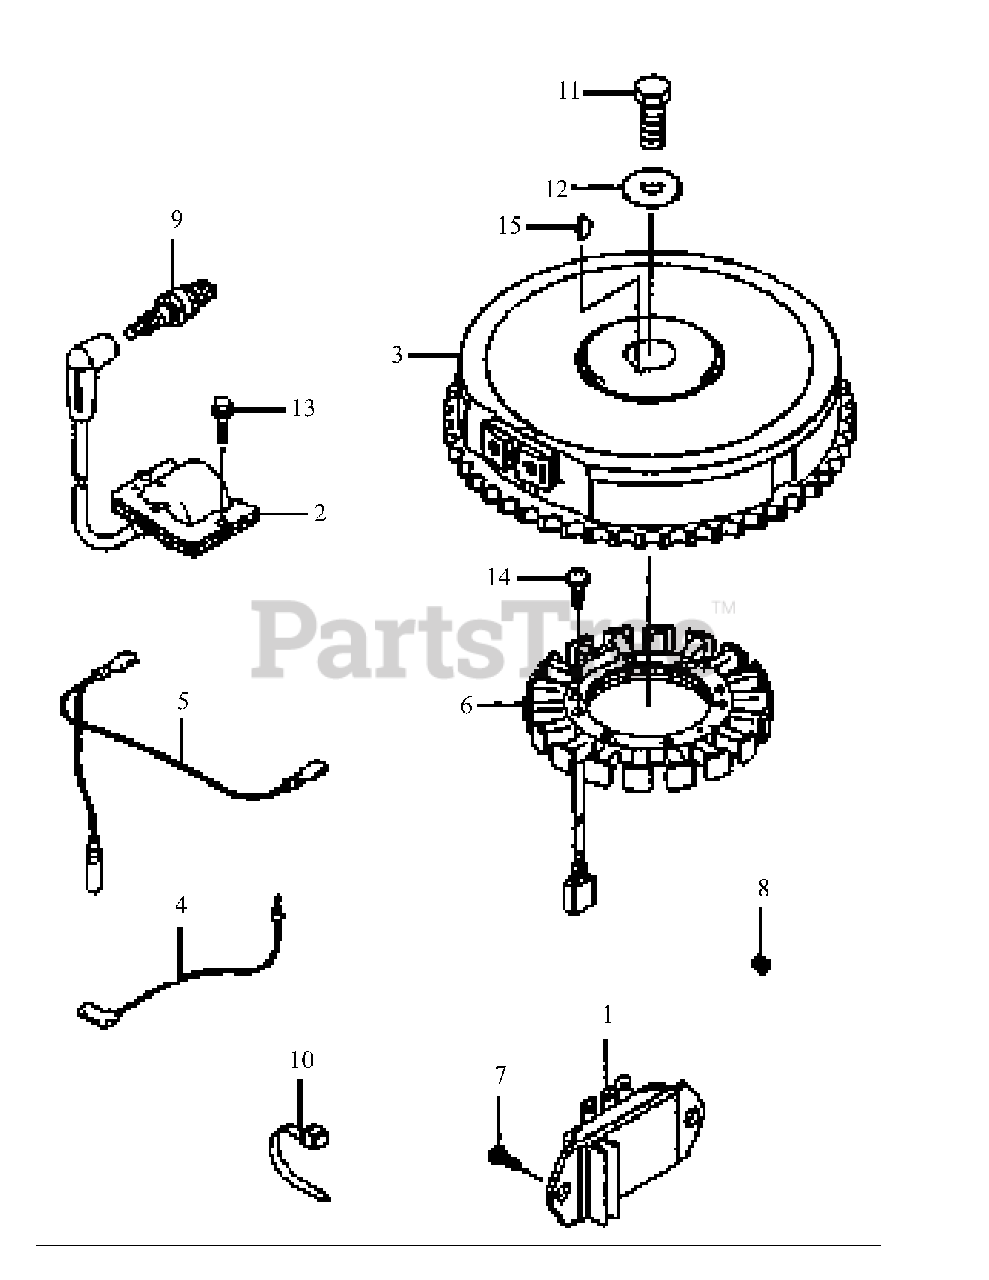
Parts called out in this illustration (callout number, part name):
1	Regulator, Voltage
2	Coil, Ignition
3	Flywheel
6	Coil, Charging
9	Spark Plug
13	Bolt, Flange
14	Screw Pan Hd.
15	Key-Woodruff
